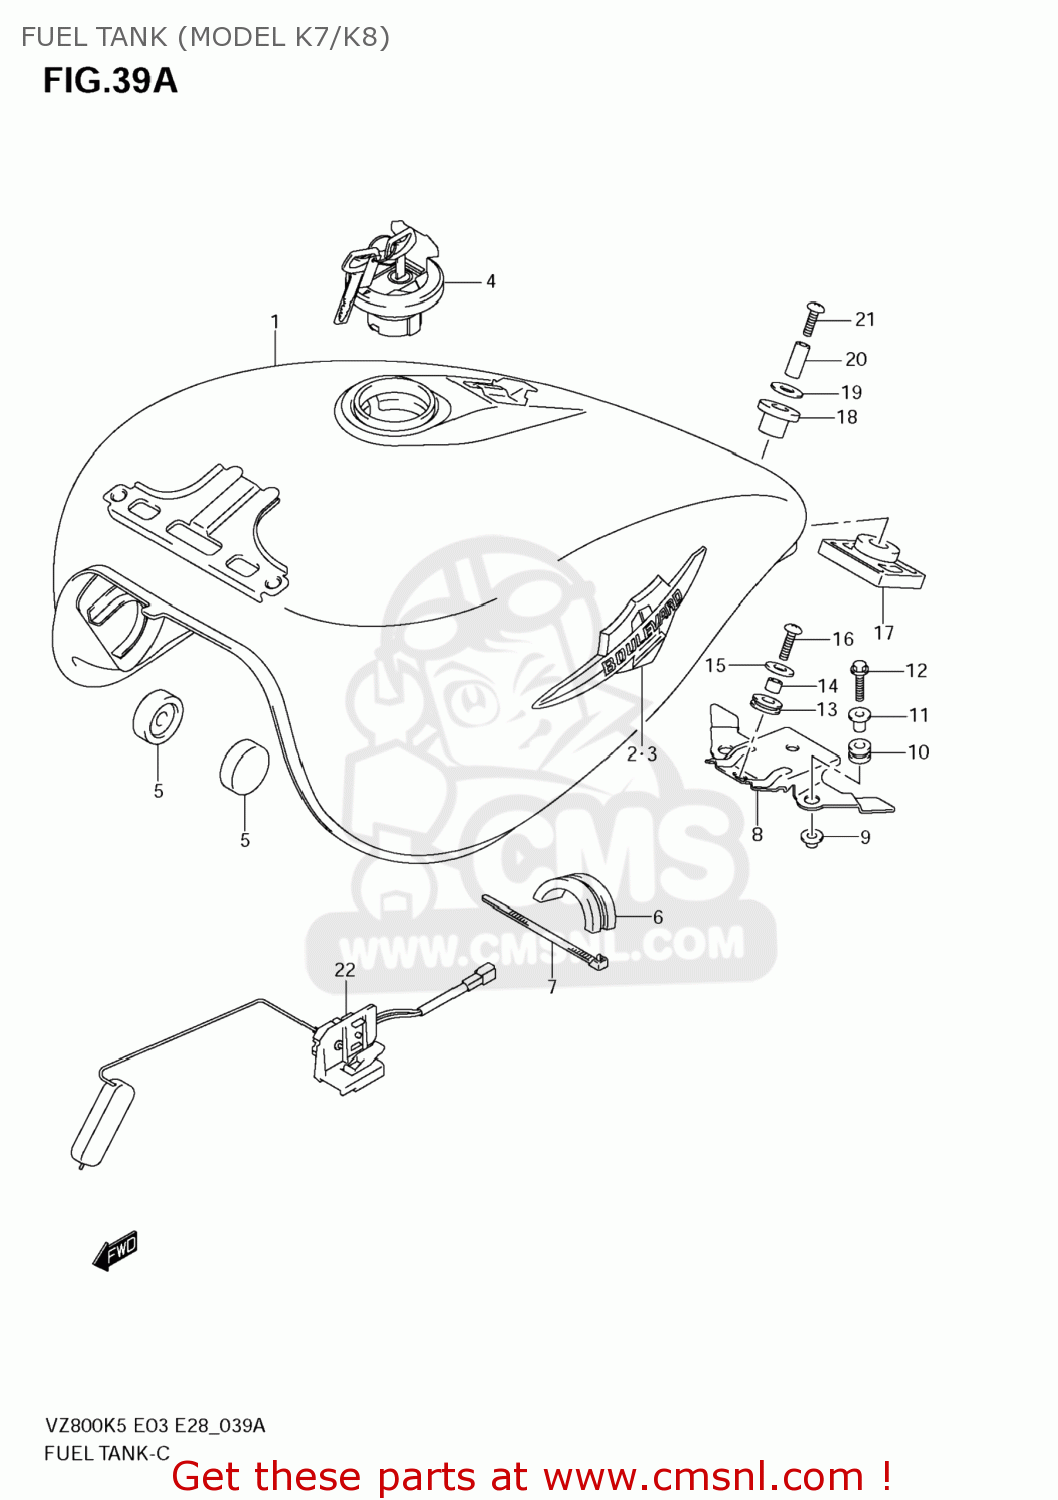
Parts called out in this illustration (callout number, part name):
1	TANK ASSY,FUEL
2	EMBLEM,FUEL TA
3	EMBLEM,FUEL TA
4	CAP SET,FUEL TANK
5	CUSHION
6	CUSHION,FUEL TANK LWR
7	CLAMP(L:250)
8	BRACKET COMP,F
9	WASHER
10	CUSHION
11	WASHER
12	SCREW
13	CUSHION
14	SPACER(8.5X12X7.5)
15	WASHER(8.5X26X1.6)
16	BOLT(8X20)
17	CUSHION,FUEL TANK RR LWR
18	CUSHION,FUEL TANK RR UPR
19	SPACER (8.2X12.5X23.5)
20	WASHER (8.5X33X1.6)
21	BOLT
22	GAUGE ASSY,FUEL LEVEL SENDER
